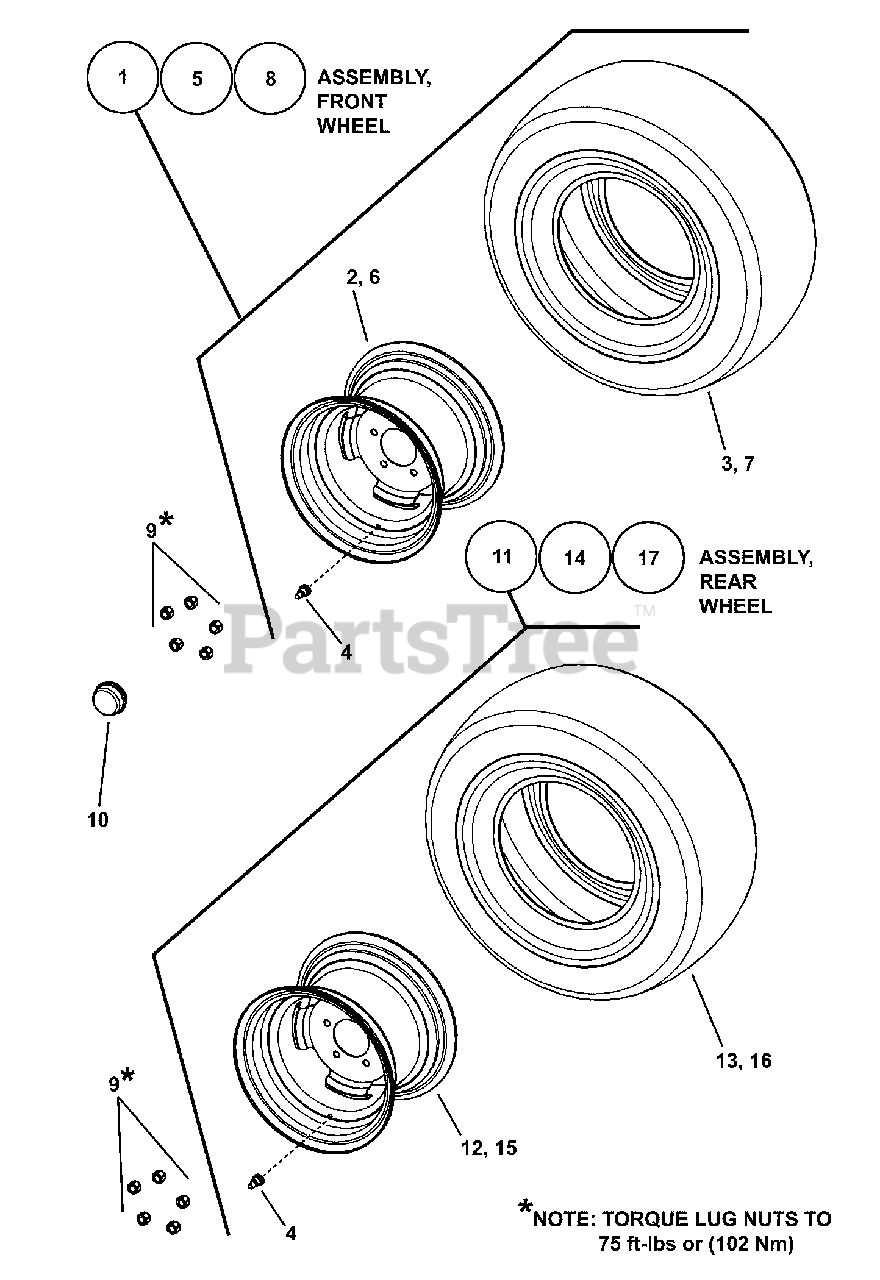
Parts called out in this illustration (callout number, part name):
1	ASSY, Front Wheel, Turf Tire (incl. Ref. #'s 2, 3 & 4)
2	RIM, 12 x 7.00 w/ 1.06 Inset
3	TIRE, Titan Multi Trac C/S, 23 x 8.50-12
4	AIR VALVE (Snap-In)
5	ASSY, Left Front Wheel (incl. Ref #'s 4, 6 & 7)
6	RIM, 10 x 6 w/1.06 Offset
7	TIRE, ATV 22 x 11 - 10 (Dirt Dog) Kenda Tire
8	ASSY, Right Front Wheel (incl. Ref. #'s 4, 6 & 7)
9	LUG NUT, 1/2-20 Hex (tapered seat)
10	DUST CAP
11	ASSY, Rear Wheel, Turf Tire (incl. Ref. #'s 4, 12 & 13)
12	RIM, 12 x 8.50 w/ .95 Offset
13	TIRE, Titan Multi Trac C/S, 26 x 12.00-12, 4P
14	ASSY, Left Rear Wheel (incl. Ref. #'s 4, 15 & 16)
15	RIM, 10 x 6 w/1.25 Offset
16	TIRE, ATV 25 x 12 - 10 (Dirt Dog) Kenda Tire
17	ASSY, Right Rear Wheel (incl. Ref. #'s 4, 15 & 16)
